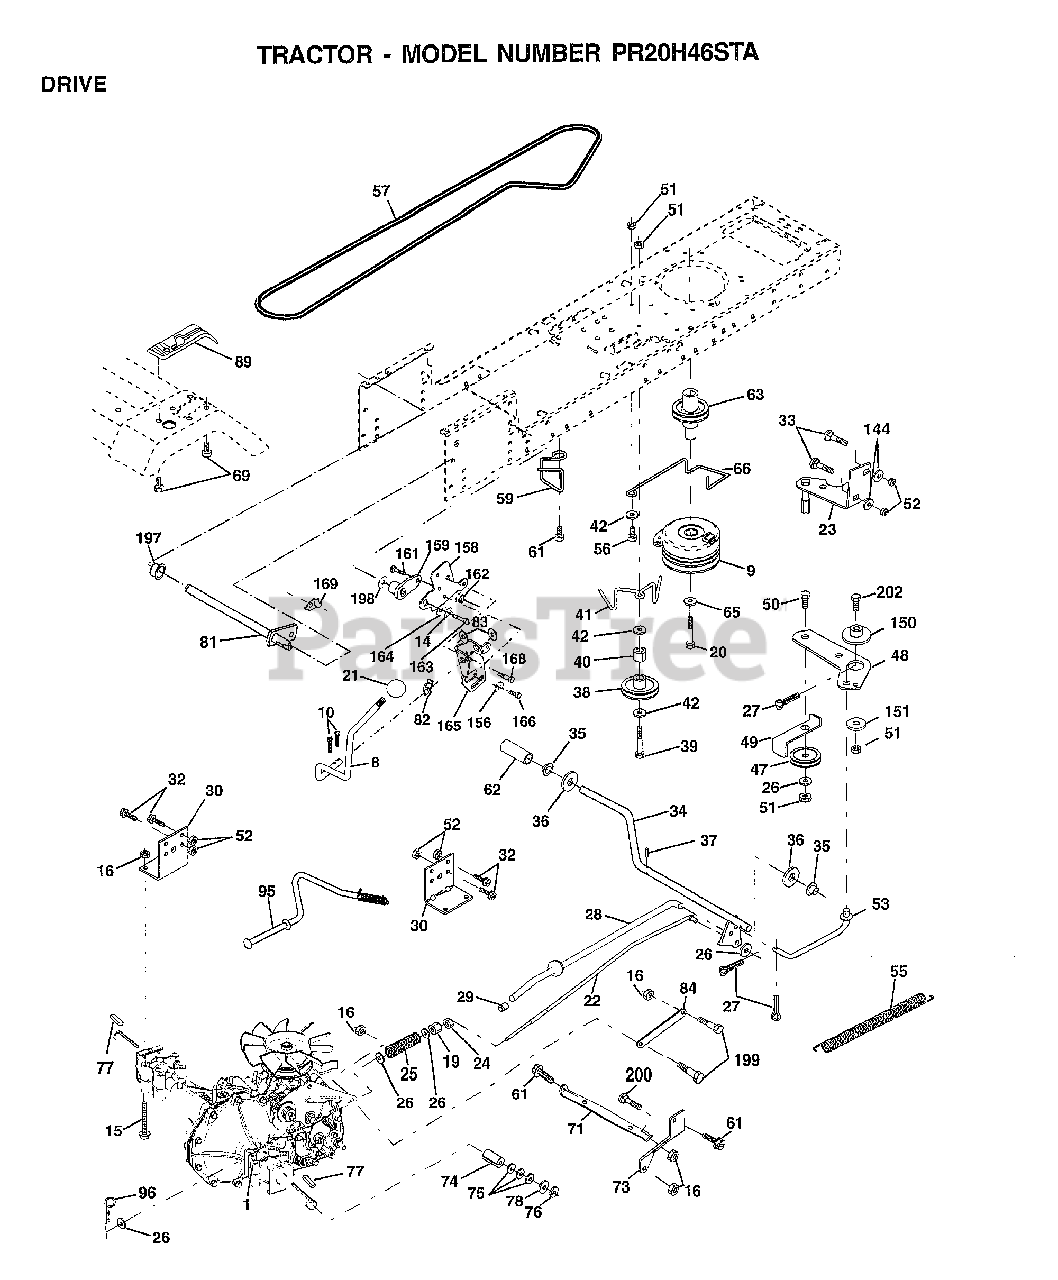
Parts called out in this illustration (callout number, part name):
8	ROD.SHIFT.FEND.ADJ.YT
9	CLUTCH.ELECTRIC
10	PIN COTTER 1/8
14	LOCKWASHER
15	BOLT.HX.FLG.5/16
16	NUT
19	NUT
20	BOLT.7/16-20X4.25
21	KNOB DLX BLK/BLK
22	ROD BRAKE HYDRO
23	BRKT ASM
24	NUT
25	SPRING ROD LT
26	WASHER
27	COTTER PIN
28	ROD.BRAKE.PARK.LT
29	PLUNGER CAP T
30	BRACKET MTG TRANSAXLE
32	BOLT
33	BOLT
34	SHAFT ASM-PEDAL F
35	NYLON BEARING
36	WASHER LT
38	FLAT IDLER PULLEY
39	BOLT
40	SPACER T
41	"KEEPER,BELT.IDLER FLAT"
42	WASHER
48	BELLCRANK.CLUTCH
49	RETAIN BELT
53	"LINK, CLUTCH T"
55	"SPRING, RETURN LT"
57	"BELT.GD DRV 82"""
59	KEEPER BELT SPAN CTR
61	SCREW
62	PEDAL COVER T
63	PULLEY.CLUTCH.EVX
65	LOCKWASHER
66	KEEPER-BELT
69	SCREW HEXWSH H-L
71	STRAP TORQUE LH HYDRO
73	STRAP TORQUE RH HYDRO
74	SPACER
75	WASHER
76	E-RING LT
77	SQUARE KEY
78	WASHER
81	SHAFT
82	"SPRING,TORSION"
83	WASHER
84	LINK TRANSAXLE
89	CONSOLE.SHIFT.AUTO.YT/GT.BLACK
95	CONTROL ASSY
96	RETAINER M
144	WASHER
150	BUSHING.BELLCRANK.GRD.DR
151	WASHER
156	WASHER.SRRTD.5/16
158	BRKT.SHIFT.MOUNT
159	HUB.SHIFT
161	BOLT T
164	WASHER.5/8X.281X10GA
165	BRKT.PIVOT.LEVER
166	SCREW.5/16-18X5/8
168	BOLT.SHOULDER.5/16-18X.561
169	PLATE.FASTENING
197	NYLINER SNAP-IN
198	WASHER NYLINER
199	BOLT SHOULDER
200	BOLT
202	BOLT.3/8-16X1.50
